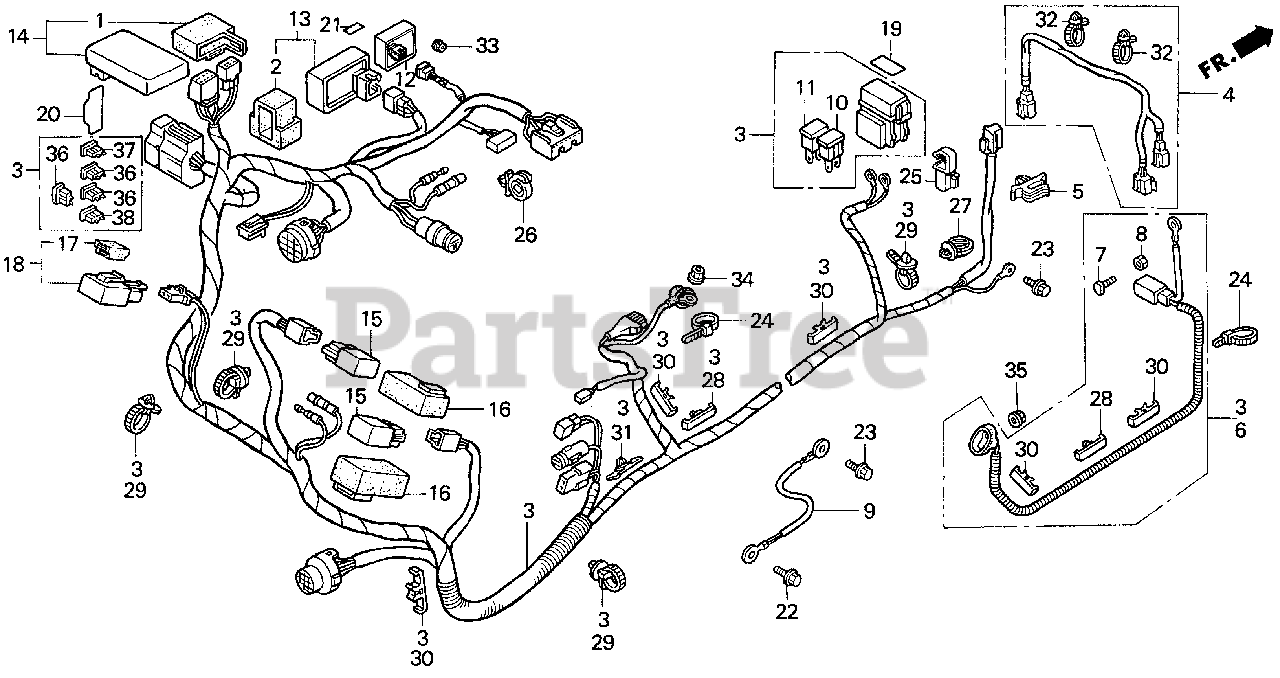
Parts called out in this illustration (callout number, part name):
1	RUBBER, IGNITION CONTROL MODULE
2	SUSPENSION, IGNITION CONTROL MODULE (NOT AVAILABLE)
3	WIRE HARNESS ASSY., MAIN
4	SUB-WIRE, HOOD
5	CLIP, WIRE HARNESS
6	CABLE ASSY., STARTER
7	BOLT, BATTERY TERMINAL
8	NUT, BATTERY TERMINAL
9	CABLE, SUB-GROUND
10	FUSE, BLOCK (50A)
11	FUSE, BLOCK (70A)
12	CONTROL UNIT, GLOW
13	CONTROL UNIT, FUEL (SINDENGEN)
14	RELAY ASSY., COMBINATION
15	RELAY, STARTER (OMRON)
16	SUSPENSION, STARTER RELAY (OMRON)
17	SUSPENSION, STARTER RELAY (TATEISHI)
18	RELAY ASSY., HAZARD
19	MARK, MAIN FUSE (ENGLISH)
20	MARK, BRANCH FUSE (ENGLISH)
21	MARK, GLOW FUSE
22	BOLT, GROUND (6X19) (SN)
23	BOLT, GROUND (6X16) (SN)
24	BAND, CABLE (120MM) (BLACK)
25	CLIP, HARNESS (5MM-15MM)
26	CLIP, WIRE HARNESS
27	CLIP, HARNESS
28	CLIP, WIRE HARNESS (BLACK)(HARNESS TAPING)
29	BAND, WIRE HARNESS (110MM) (BROWN)
30	CLIP, WIRE HARNESS (BLACK)
31	CLIP, WIRE HARNESS (WHITE)
32	BAND, WIRE HARNESS (94MM) (WHITE)
33	NUT, FLANGE (6MM)
34	NUT-WASHER (6MM)
35	NUT-WASHER (8MM)
36	FUSE, BLADE (5A)
37	FUSE, BLADE (10A)
38	FUSE, BLADE (15A)
